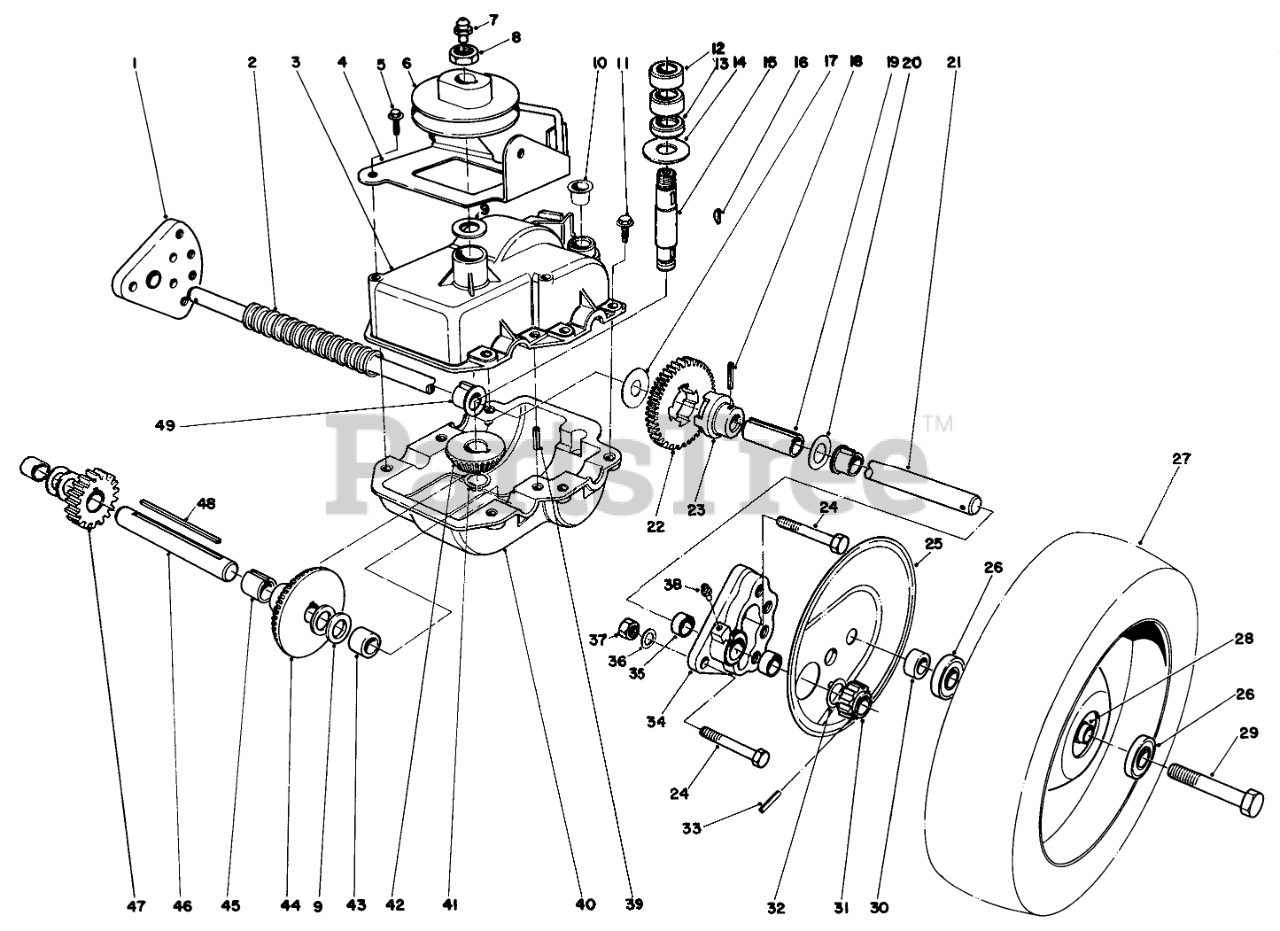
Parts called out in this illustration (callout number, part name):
1	Wheel Quadrant Assembly "B" (Incl. Ref. #35 & 37)
2	Cover-Drive Shaft
3	Case-Upper
4	BELT GUIDE BRKT WA
5	SCREW
6	PULLEY
7	FITTING-GREASE
8	NUT-HEX
9	WASHER-THRUST
10	Caplug
11	SCREW-HWHTF
12	BEARING-NEEDLE
14	WASHER-THRUST
15	Shaft Input
16	KEY-WOODRUFF
17	WASHER
18	PIN-SPIROL
19	Spacer-Output Shaft
20	WASHER-PLAIN
21	Shaft-Output
22	Gear
23	ADAPTER DRIVE
24	SCREW-HH
25	WHEEL COVER
26	Bearing-Flanged
27	Wheel & Tire Assembly (Incl. Ref. #26)
28	SPACER-BEARING
29	SCREW-HH
30	SPACER-WHEEL
31	PINION GEAR 15T
32	THRUST WASHER
33	Pin-Groove
34	Wheel Quadrant "A" (Incl. Ref. #35 & 37)
35	Bearing-Needle
36	WASHER-FLAT
37	NUT-LOCK, NI
38	FITTING-GREASE
39	ROLL PIN 3/16 X 1 IN
40	Case-Lower
41	RING-RETAINING
42	PINION-BEVEL
43	BEARING-NEEDLE, CLOSED
44	BEVEL GEAR
45	Spacer-Short Shaft
46	Shaft-Intermediate
47	16 T GEAR
48	Key Square
49	BUSHING
